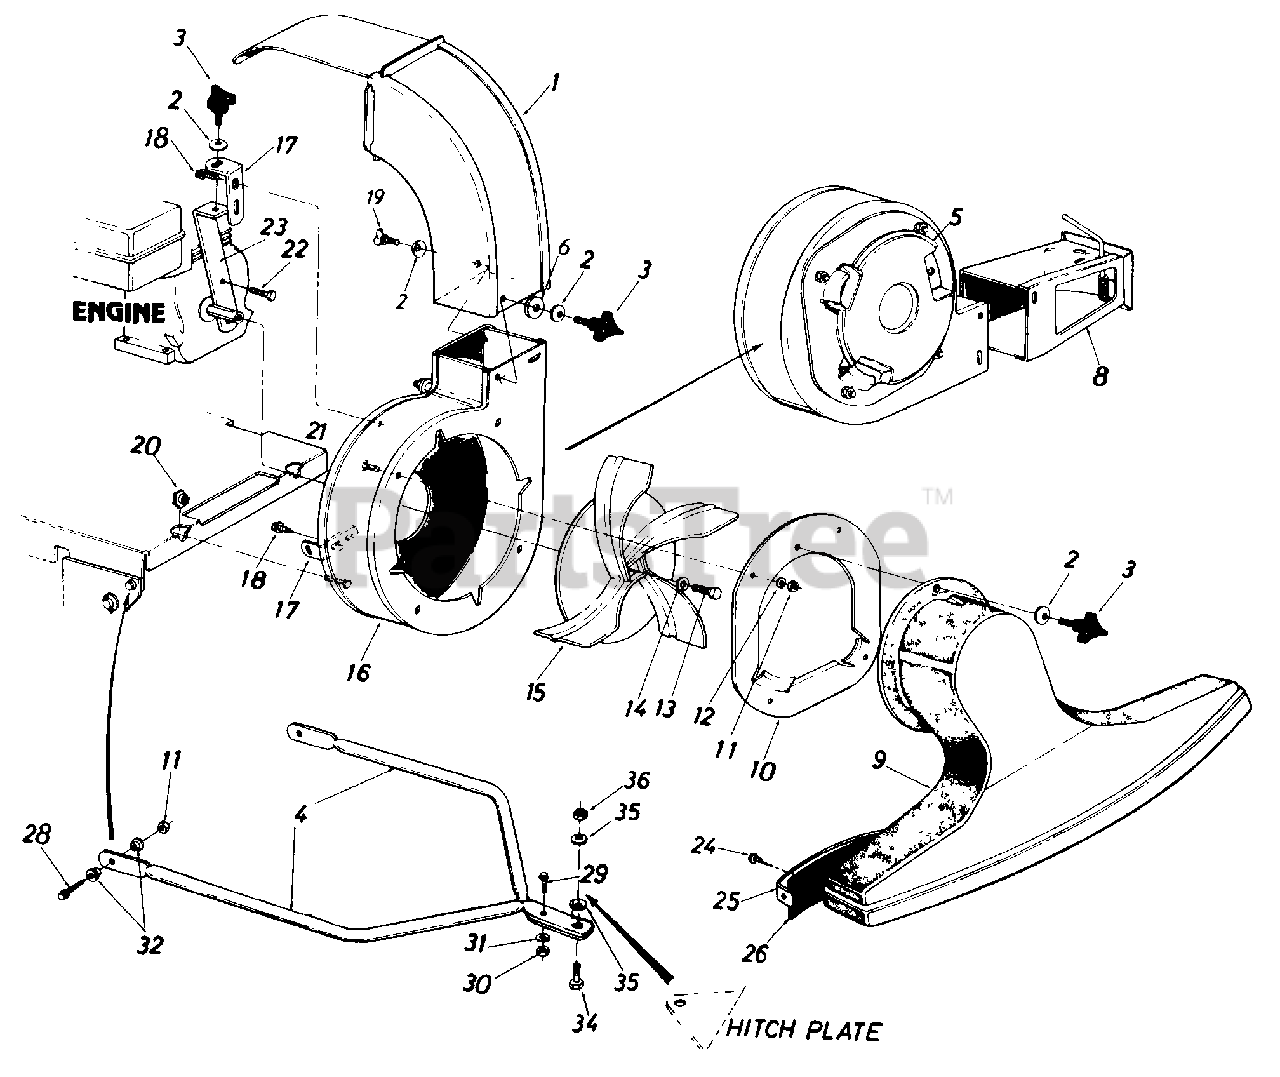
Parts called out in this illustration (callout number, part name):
3	Hand Knob
6	Fl-Wash. .344" I.D. x 1.125" O.D.
10	Nozzle Plate Ass'y.
11	Hex Nut 5/16-18 Thd.
12	L-Wash. 5/16" I.D.
13	Hex Bolt 3/8-24 x 1.25" Lg.
14	L-Wash. 3/8" I.D. H.D.
15	Air Vane Plate Ass'y. w/Pulley
19	Thumb Screw 5/16-18
20	Hex Shoulder Nut .50 I.D.
21	Carriage Bolt 5/16-18 x .62"
22	Hex Locking Bolt 5/16-24 x .75" Lg.
28	Hex Bolt 5/16-18 x 1.00" Lg.
29	Truss Mach. Scr. 1/4-20 x .75
30	Hex Nut 1/4-20 Thd.
31	L-Wash. 1/4 I.D.
32	Shoulder Spacer
34	Shld. Bolt .496 Dia.
35	Belleville Wash. .39" I.D. x 1.12" O.D.
36	Hex Jam L-Nut 3/8-26 Thd.
